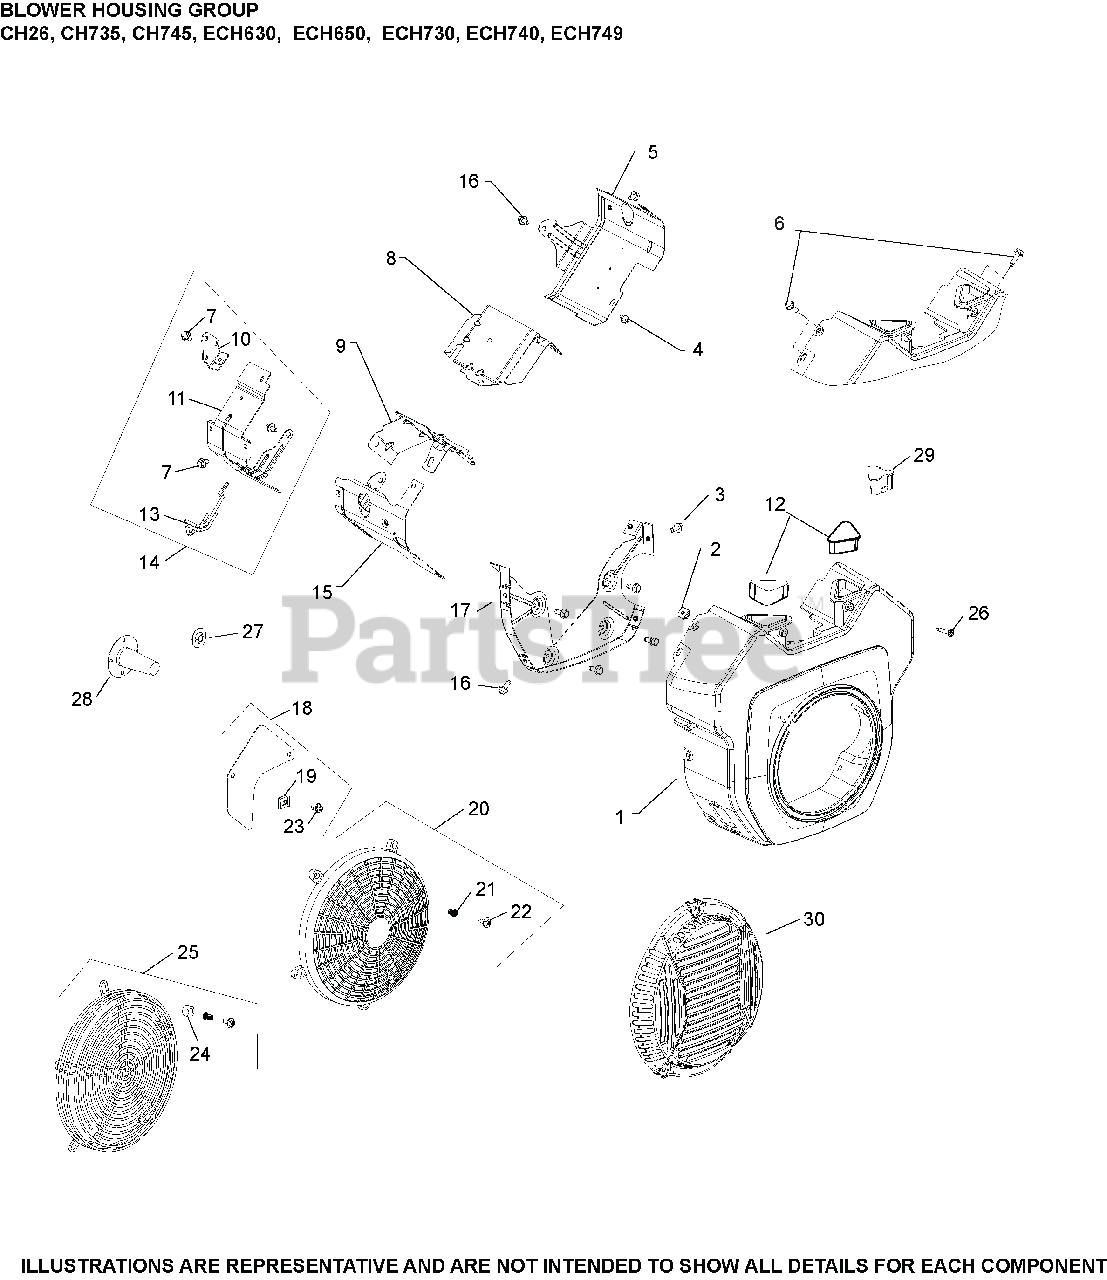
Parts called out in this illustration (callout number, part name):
1	HOUSING, BLOWER
3	SCREW, THREAD FORMING
4	SCREW, THREAD FORMING
5	BAFFLE, RIGHT BARREL
6	SCREW, THREAD FORMING
8	BAFFLE, VALLEY #1 CYLINDER
9	BAFFLE, VALLEY #2 CYLINDER
15	BAFFEL, LEFT BARREL
16	SCREW, THREAD FORMING
17	PLATE, BACKING
17	KIT, BACKING PLATE
20	KIT, FIXED GUARD
22	SCREW, SEMS
29	COVER, BLOWER HOUSING
